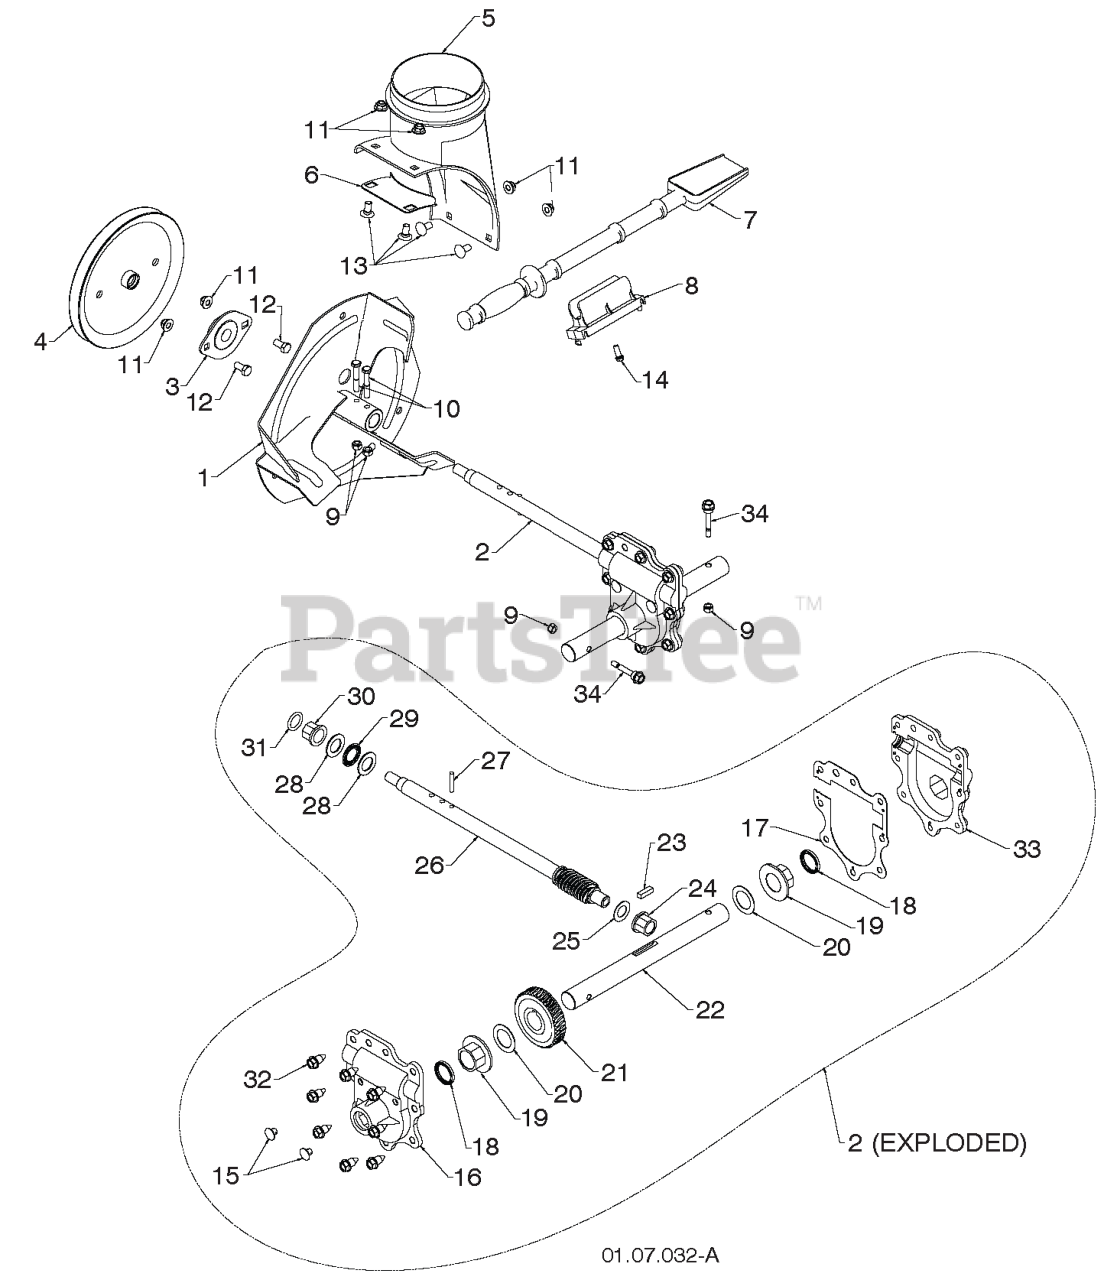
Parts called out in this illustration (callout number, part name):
1	CABLE.POWER STEERING.LHS
2	CABLE.POWER STEERING.RHS
3	LEVER CONTROL DSST OPP MPP
4	LEVER.CABLE.ARM.LHS.BLACK
5	LEVER.CABLE.ARM.RHS.BLACK
6	SCREW HEX_WASH_13-16 X 1.50_H
7	SCREW 14-20 X 5/8
8	SCREW.HWH.13-16X.50
9	PIN.GROOVED
